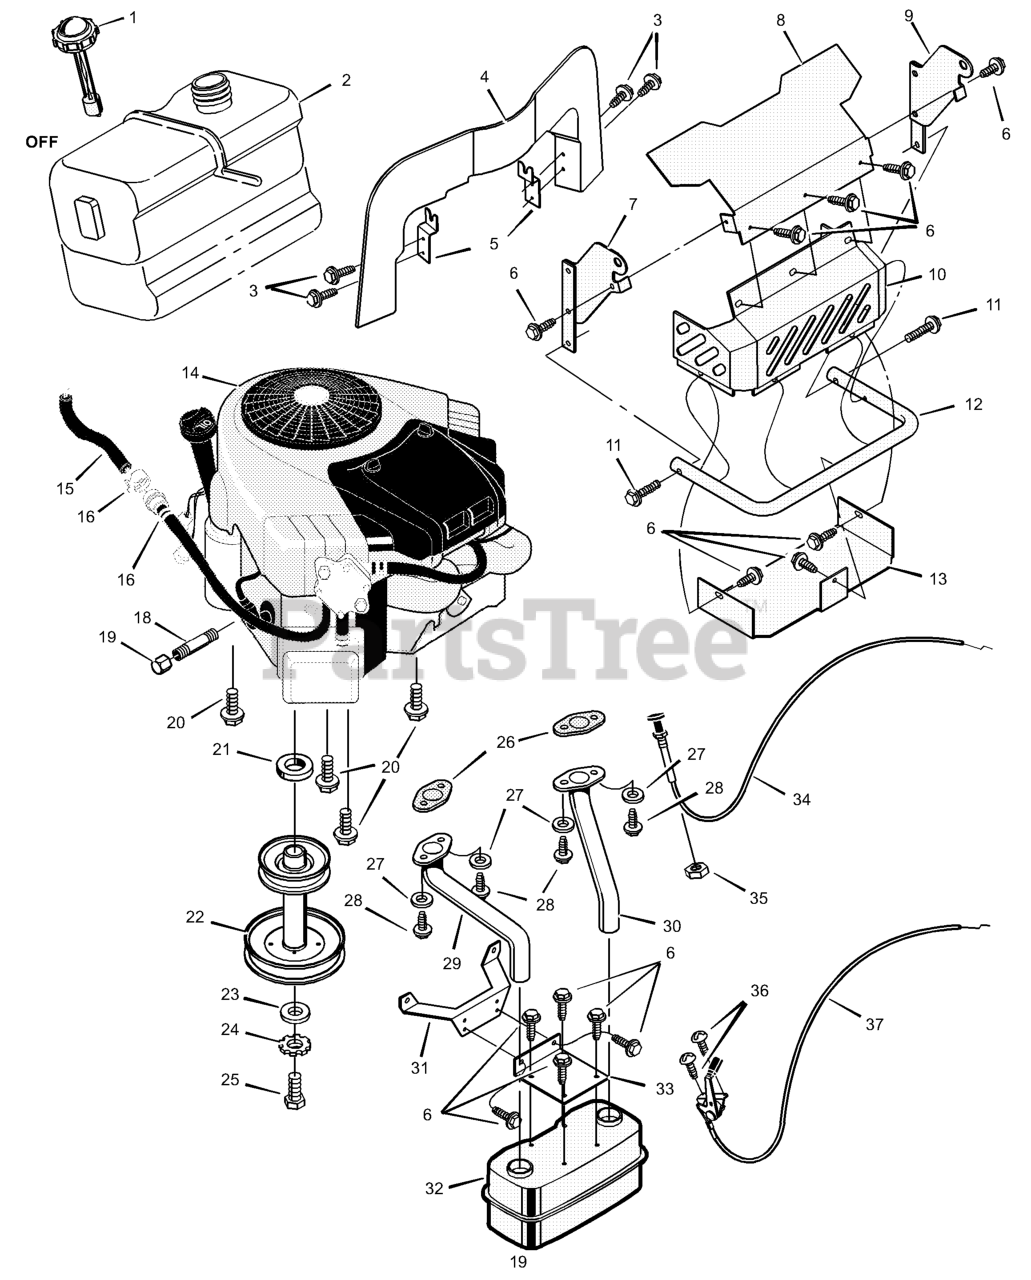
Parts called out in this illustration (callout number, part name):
1	Cap, Fuel
2	Tank, Fuel
3	Screw
4	Baffle
5	Clip, Baffle Mounting
7	Assembly, Right Grille Support
8	Shield, Heat
9	Assembly, Left Grille Support
10	Shield, Heat
13	Shield, Lower
14	Engine *
15	Fuel Line (Must cut to length)
16	Clamp
18	Pipe, Oil Drain
19	Cap, Oil Drain
20	Bolt
22	Pulley, Stack
24	Lockwasher
27	Washer
28	Bolt
29	Tube, Right Exhaust
30	Tube, Left Exhaust
31	Bracket, Muffler Mount
32	Muffler
33	Bracket, Muffler
35	Nut
37	Control, Throttle
